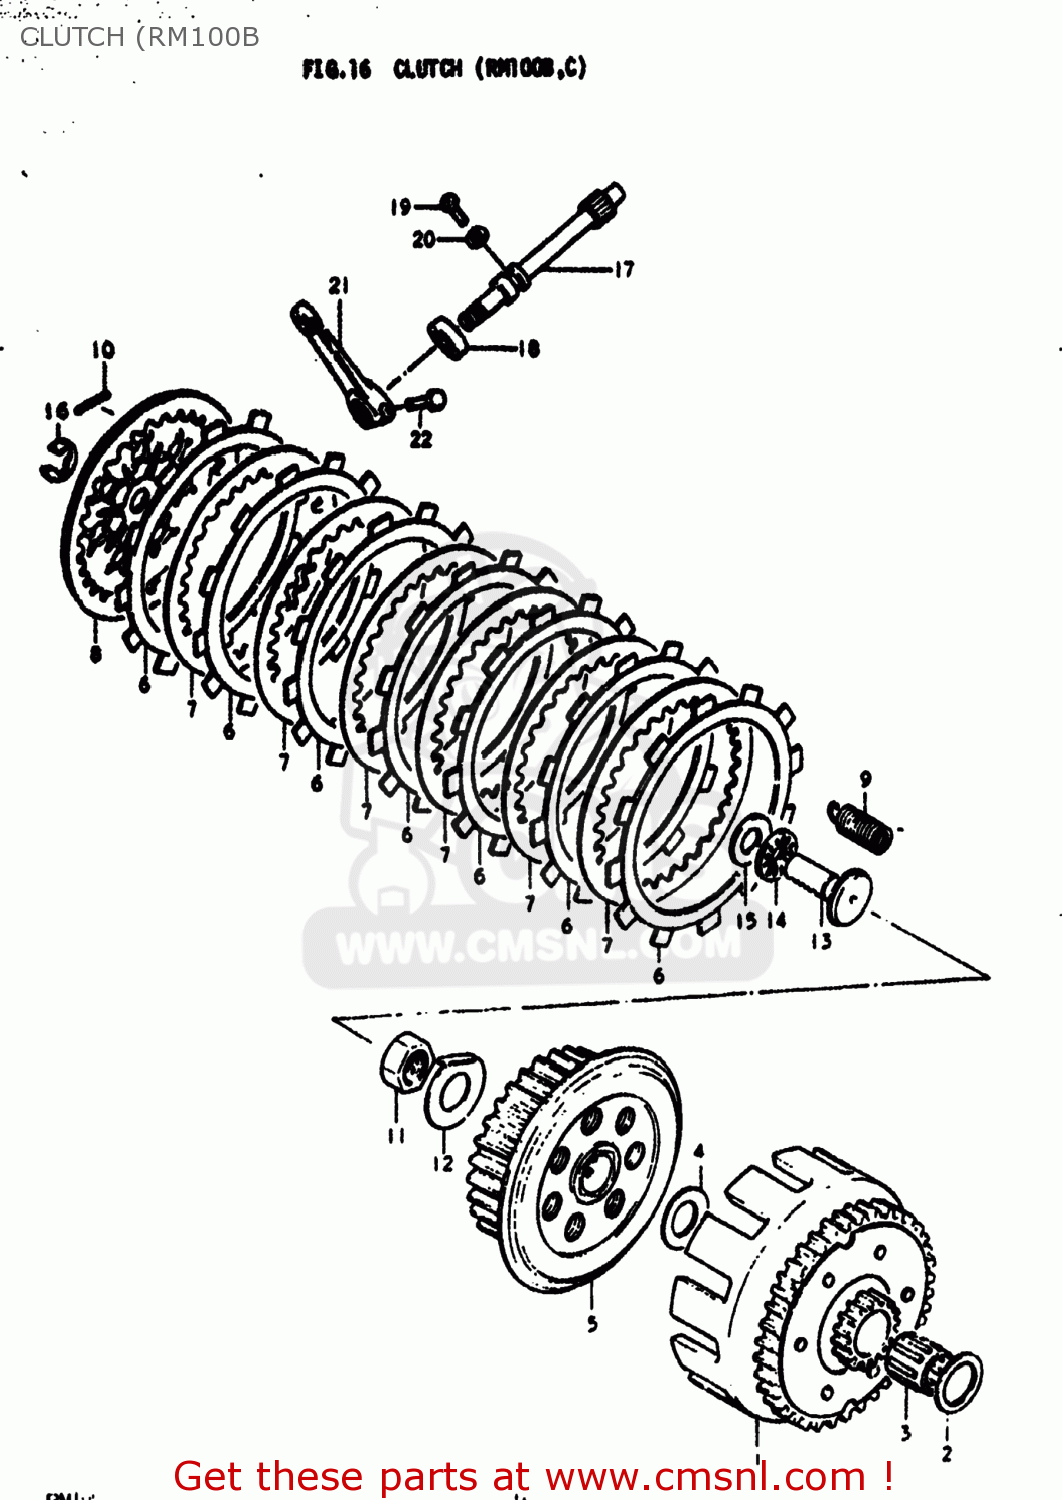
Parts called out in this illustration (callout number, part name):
1	GEAR ASSEMBLY,PRIMARY DRIVE
2	WASHER
3	BEARING(20X25X26)
4	WASHER
5	HUB,CLUTCH SLEEVE
6	PLATE,CLUTCH DRIVE
7	PLATE,CLUTCH DRIVEN
8	PLATE,CLUTCH PRESSURE
9	SPRING
10	PIN(2.5X19.8)
11	NUT
12	WASHER,LOCK
13	RACK,CLUTCH RELEASE
14	BEARING(10X22X2.8)
15	WASHER
16	E RING 8MM
17	PINION,CLUTCH RELEASE
18	SEAL,OIL (10X17X5)
19	BOLT(6X12)
20	WASHER
21	ARM,CLUTCH RELEASE
22	BOLT, UPPER
